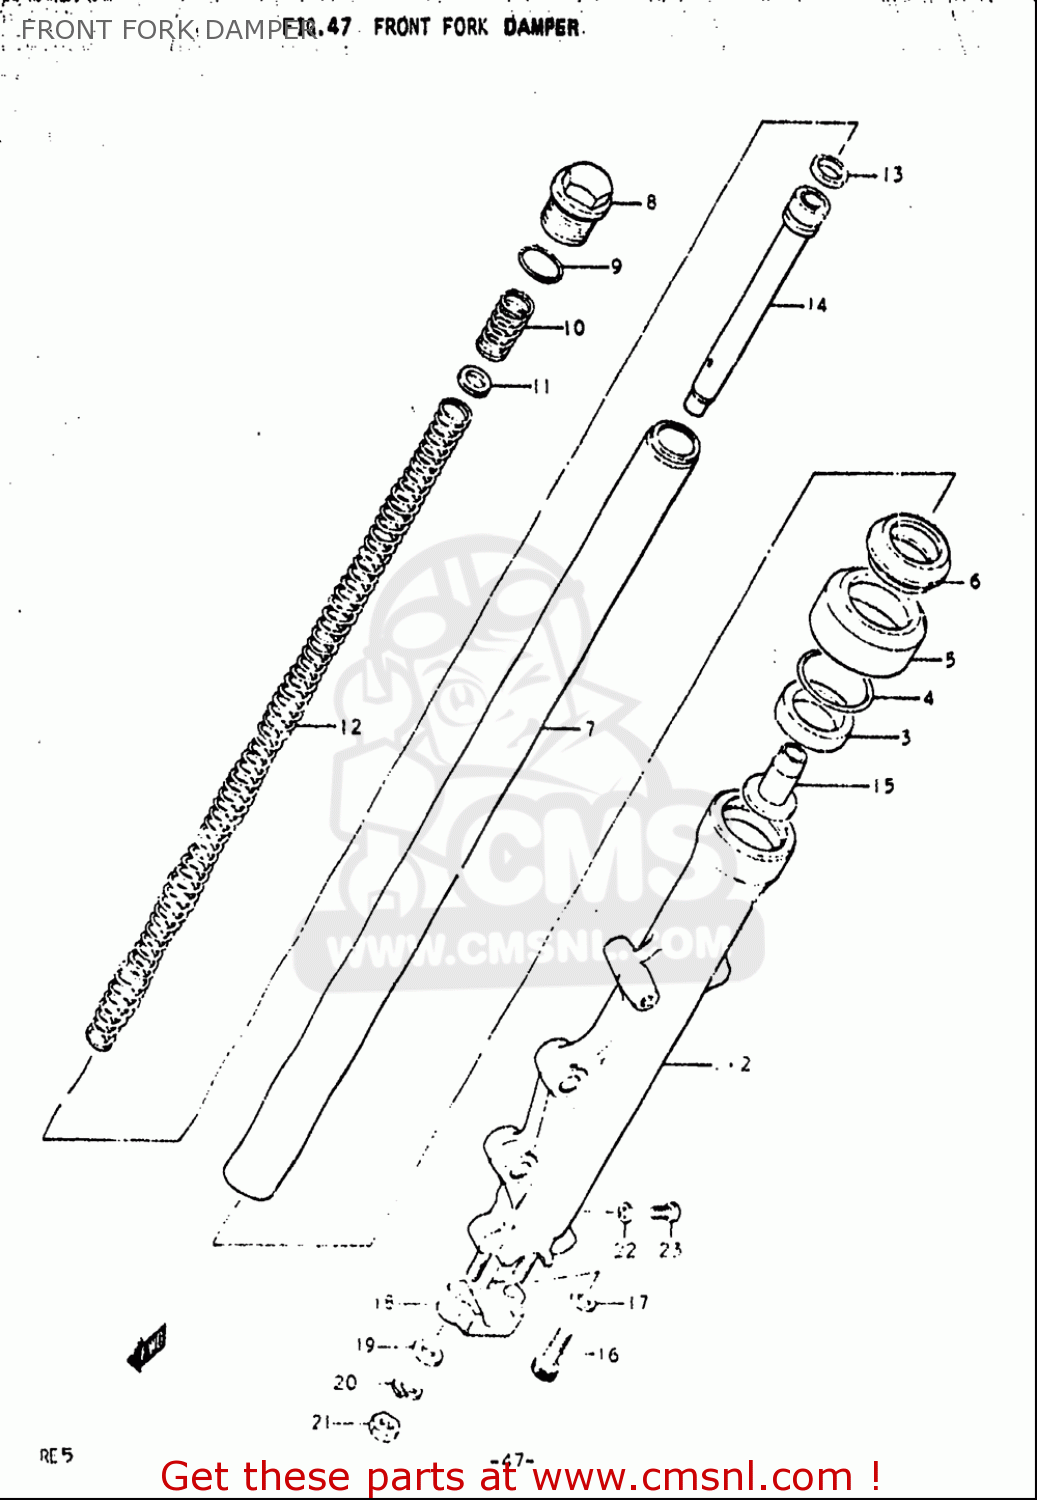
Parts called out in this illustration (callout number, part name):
3	SEAL,OIL 35X48X11
6	DUST SEAL,FR FORK
8	CAP,INNER TUBE
9	O RING
13	RING
15	PIECE,OIL LOCK
16	BOLT(8X27)
17	GASKET (NAS)
18	HOLDER,AXLE
19	WASHER
20	WASHER,LOCK
21	NUT
22	GASKET (NAS)
23	SCREW 4X6
